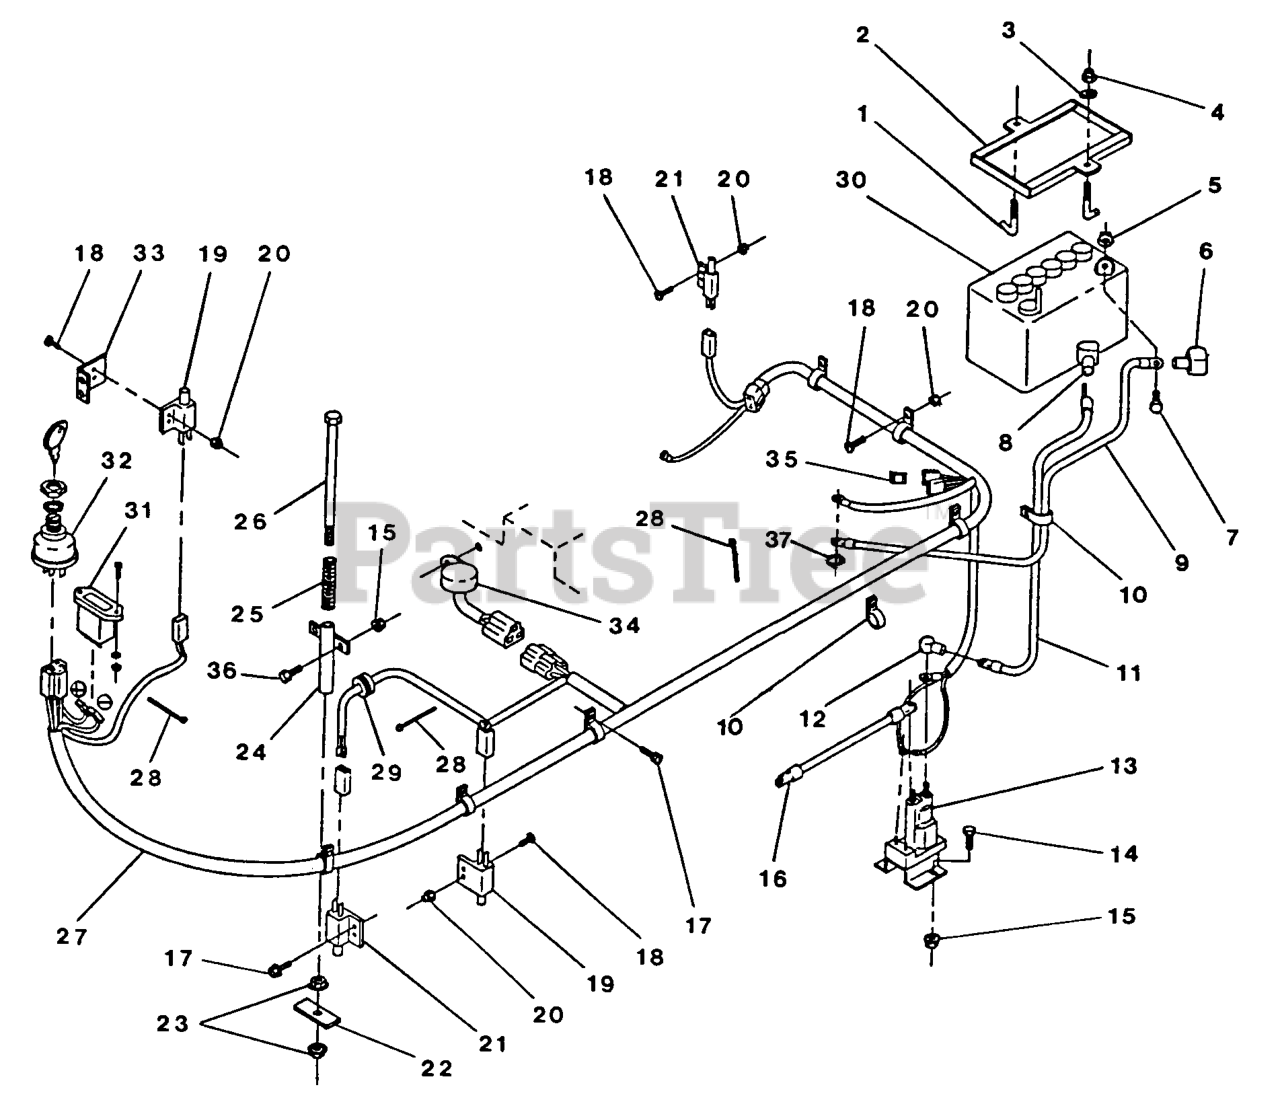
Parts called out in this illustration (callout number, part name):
1	BOLT,HOLDDOWN
2	WLD,HOLDDOWN BATTERY
6	INSULATOR, BATTERY -
10	CLIP-LOOM
12	INSULATOR-SOLENOID
17	SCREW
19	SWITCH-OPEN, NORMALLY
21	SWITCH-CLOSED, NORMALLY
22	PLATE-SWITCH, SEAT
25	SPRING-RETURN, NEUTRAL
26	SCREW-HH
28	TIE-CABLE
29	GROMMET,.38 HOLE
31	METER-HOUR
33	BRACKET,PTO SWITCH MOUNT
35	FUSE-BLADE TYPE, 20 AMP
